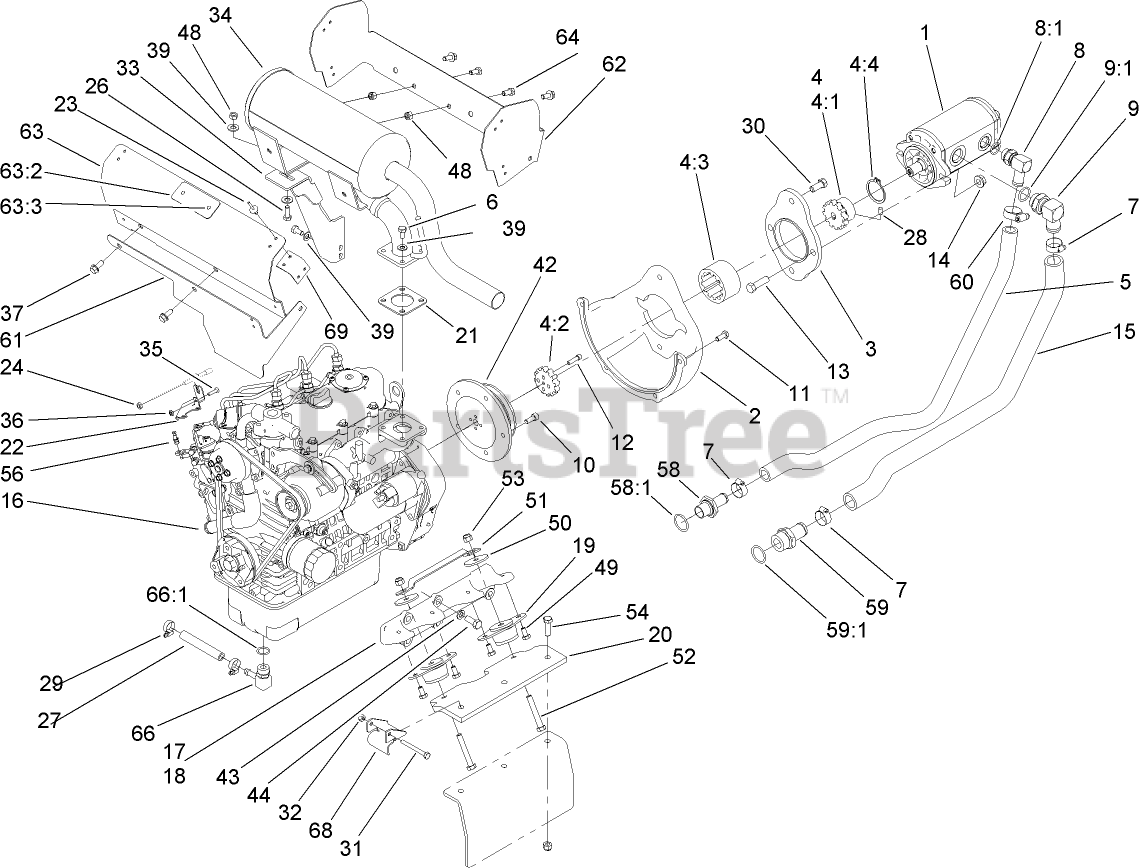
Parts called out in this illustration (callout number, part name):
1	PUMP-HYD
2	PUMP-MOUNT
3	PLATE-MOUNT, PUMP
4	COUPLING ASM
4:1	HUB-COUPLING
4:2	SLEEVE-HUB
4:3	SLEEVE-COUPLING
4:4	RING-SNAP, COUPLING
5	HOSE-FORMED, SUCTION
6	BOLT
7	CLAMP-HOSE
8	FITTING
8:1	O-RING
9	FITTING-HYD, 90 DEG
9:1	O-RING
10	SCREW-CAP, HSH
11	SCREW-HH
12	SCREW-HSH
13	SCREW-HH
14	NUT-HF
15	HOSE-FORMED, SUCTION
16	ENGINE-KUBOTA
17	MOUNT-ENGINE, LH
18	MOUNT-ENGINE, RH
19	MOUNT-ENGINE
20	PLATE-MOUNT, ENGINE
21	GASKET-MUFFLER
22	BRACKET-SUPPORT, THROTTLE
23	RIVET
24	NUT-JAM
26	SCREW-HH
27	HOSE-DRAIN
28	SCREW-SET, HSH
29	CLAMP-HOSE
30	SCREW-HH
31	SCREW-HH
32	NUT-LOCK, CONE
33	SUPPORT-MUFFLER
34	MUFFLER ASM
35	SCREW-TORX
36	NUT-HEX
37	SCREW-HHF
39	WASHER-PLAIN
42	PULLEY
43	WASHER-LOCK, SPRING
44	SCREW-HH
48	NUT-LOCK, CONE
49	SCREW-HH
50	WASHER-REBOUND
51	STRAP-REBOUND
52	SCREW-HH
53	NUT-LOCK, NI
54	SCREW-HH
56	SWIVEL-STOP, CABLE
58	FITTING-HOSE, BARBED
58:1	O-RING
59	FITTING-STR
59:1	O-RING
60	CLAMP-HOSE
61	PLATE-BAFFLE, LOWER
62	PLATE-BAFFLE
63	HEAT SHIELD BAFFLE ASM
63:2	PLATE-HOT SURFACE
63:3	RIVET-POP
64	SCREW-HH
66	FITTING-BARBED-90
66:1	WASHER-SEAL, BONDED
68	GUIDE-CABLE
69	BRACKET-SHIELD
